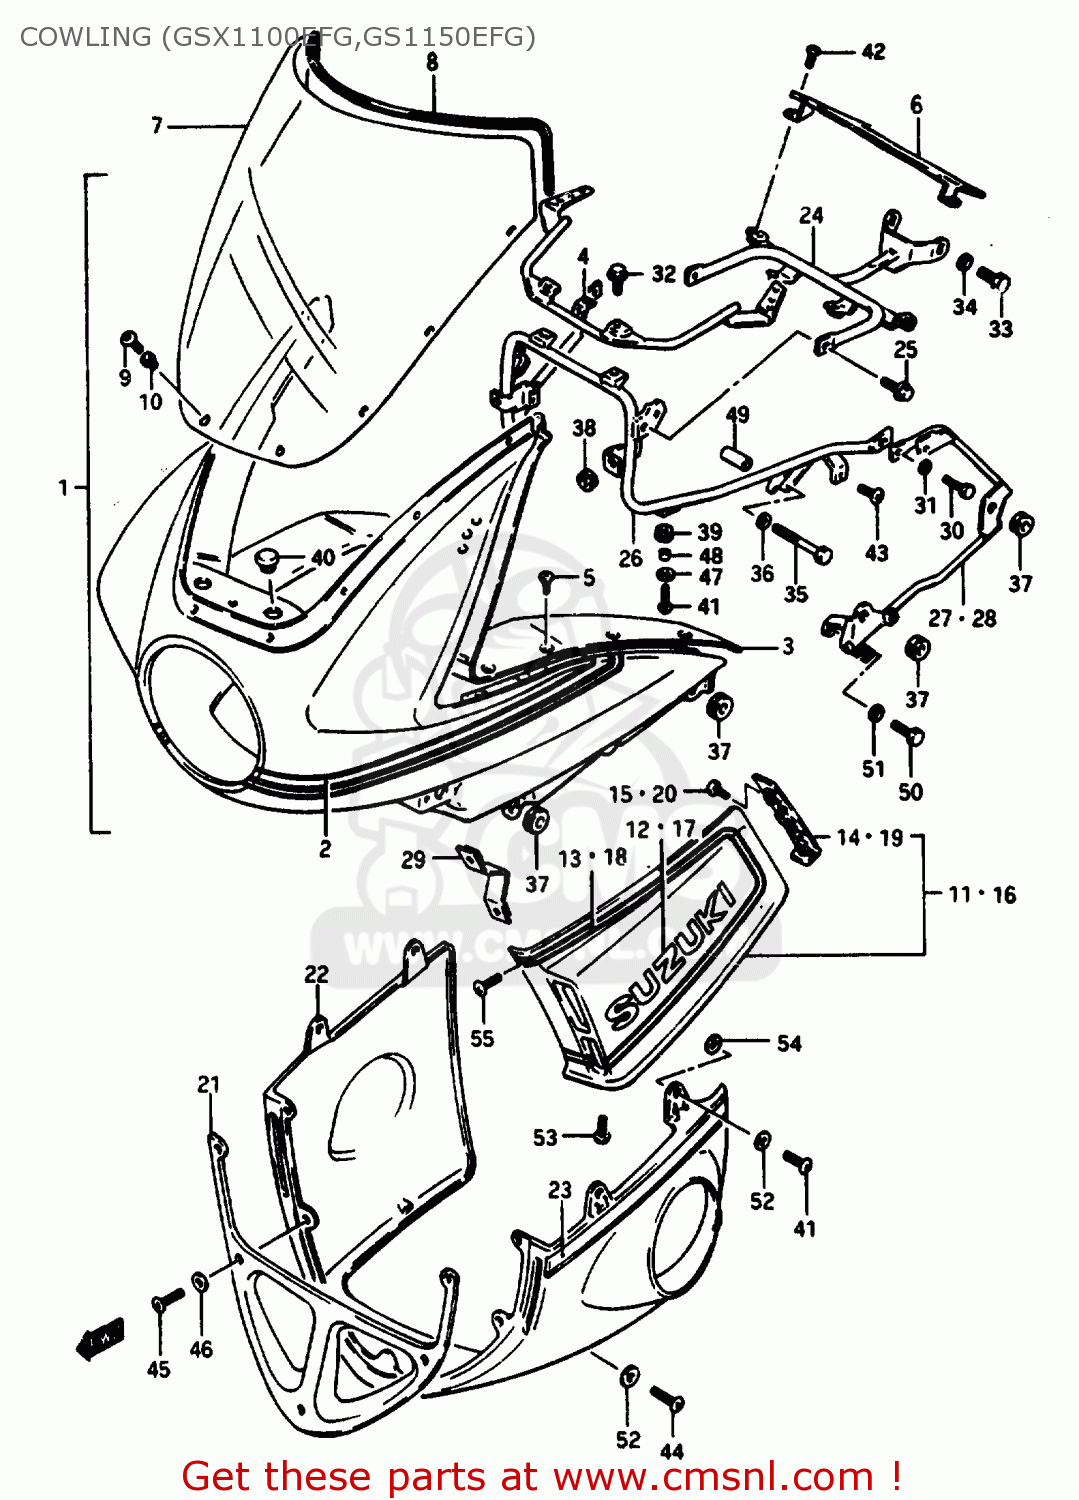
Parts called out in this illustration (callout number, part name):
1	COWLING ASSY (WHITE/RED)
2	TAPE SET
3	PANEL,COWLING
4	BRACE,COWLING BODY
5	SCREW, PANEL
6	COVER,METER,REAR
7	SCREEN
8	MOLDING
9	SCREW(5X20)
10	CUSHION
11	COVER, RH (WHITE/RED)
12	EMBLEM
13	TAPE SET, RH
14	PANEL,COWL SIDE COVER RR RH
15	SCREW
16	COVER, LH (WHITE/RED)
17	EMBLEM
18	TAPE SET, LH
19	PANEL,COWLING SIDE COVER
20	SCREW
21	COVER, LOWER (RED)
22	COVER (WHITE/RED)
23	TAPE SET
24	BRACE,COWLING,FRONT
25	BOLT
26	BRACE,COWL RR
27	BRACE,COWLING SIDE,RIGHT
28	BRACE,COWLING SIDE,LEFT
29	BRACE,SIDE,FRONT
30	BOLT 6X16
31	WASHER,LOCK
32	BOLT
33	BOLT
34	WASHER,LOCK,8.
35	BOLT
36	WASHER,LOCK,8.
37	CUSHION
38	CUSHION
39	CUSHION
40	PLUG(OD:22)
41	SCREW, CENTER
42	SCREW 5X10
43	SCREW 6X12
44	SCREW, CENTER
45	SCREW
46	WASHER
47	WASHER(6.5X18X1)
48	SPACER (6.1X9X9)
49	SPACER (8.6X13.8X35)
50	BOLT
51	WASHER,LOCK,8.
52	WASHER
53	SCREW
54	WASHER(6X13X2)
55	SCREW
